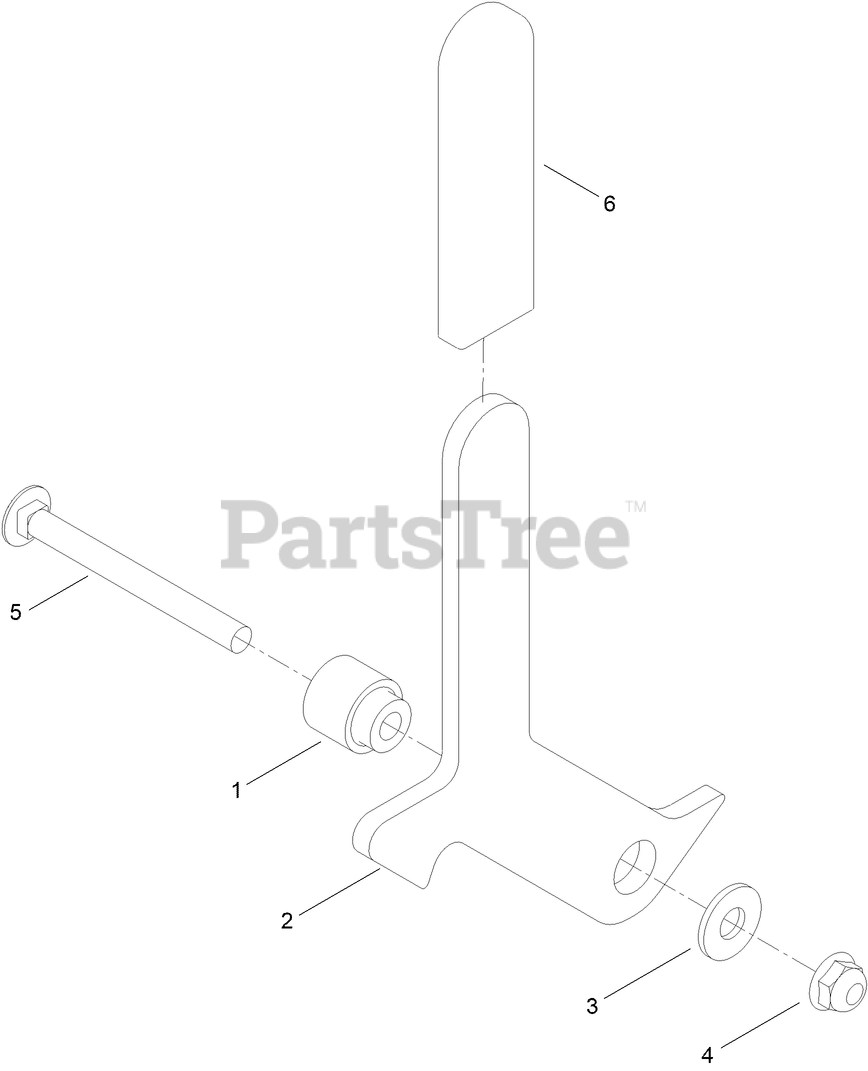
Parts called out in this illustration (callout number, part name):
1	SPACER-STEPPED
2	PLATE-TRANSPORT LOCK
3	WASHER-PLAIN
4	NUT-HF
5	SCREW-CARR
6	GRIP-HANDLE
